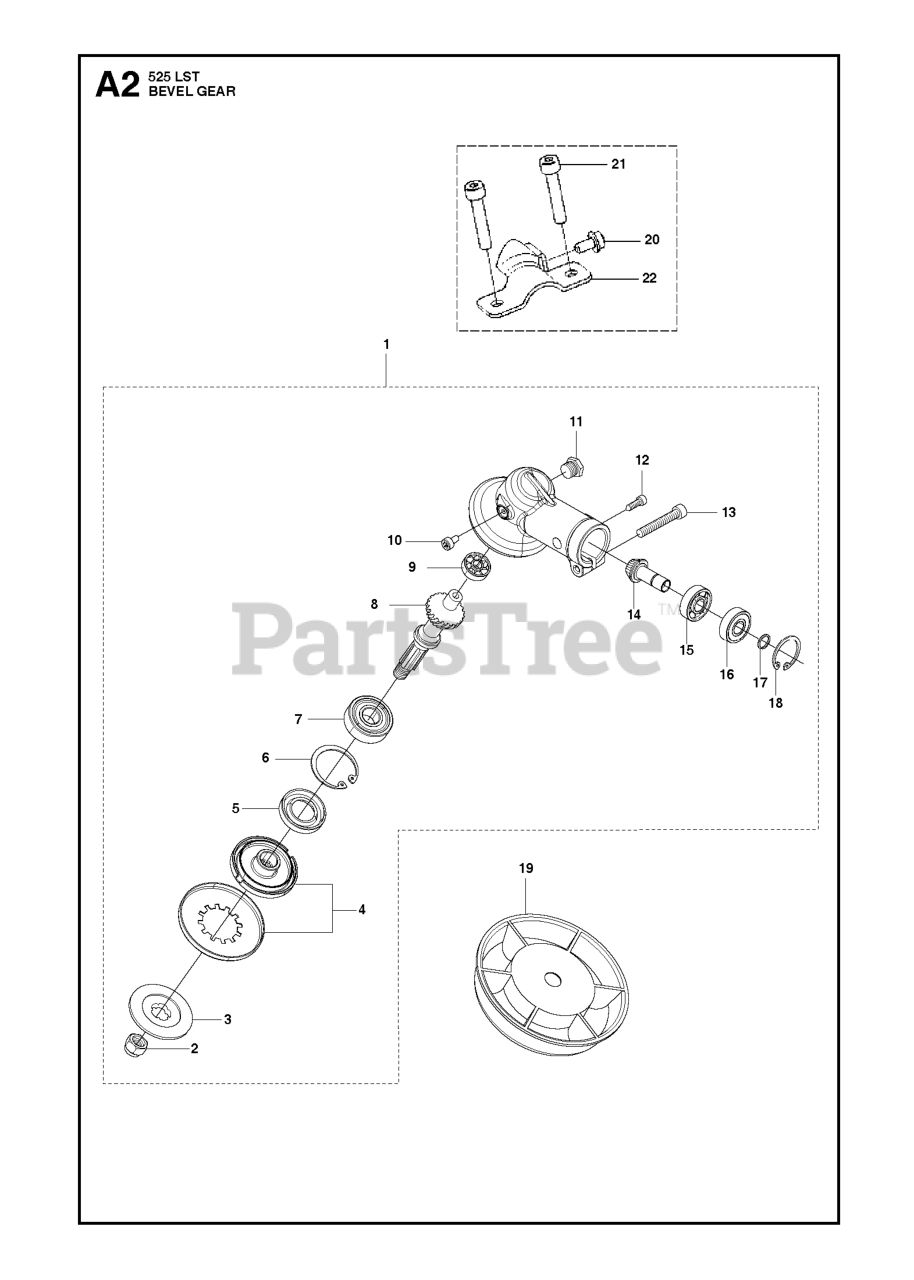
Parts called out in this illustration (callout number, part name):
1	BEVEL GEAR ASSY
2	GEARHEAD NUT - BRUSHCUTTER
3	SUPPORT FLANGE
4	DRIVER ASSY
7	BEARING***
9	BEARING (RPLS T330013520)
11	SCREW M10X1.25 T27
12	BOLT (RPLS T495051010-11)
13	BOLT M5X20 T27
14	PINION HIGH REDUCTION RATIO
18	RP_RING
19	SUPPORTING CUP
20	BOLT (RPLS T495051010-11)
21	BOLT, TORX
